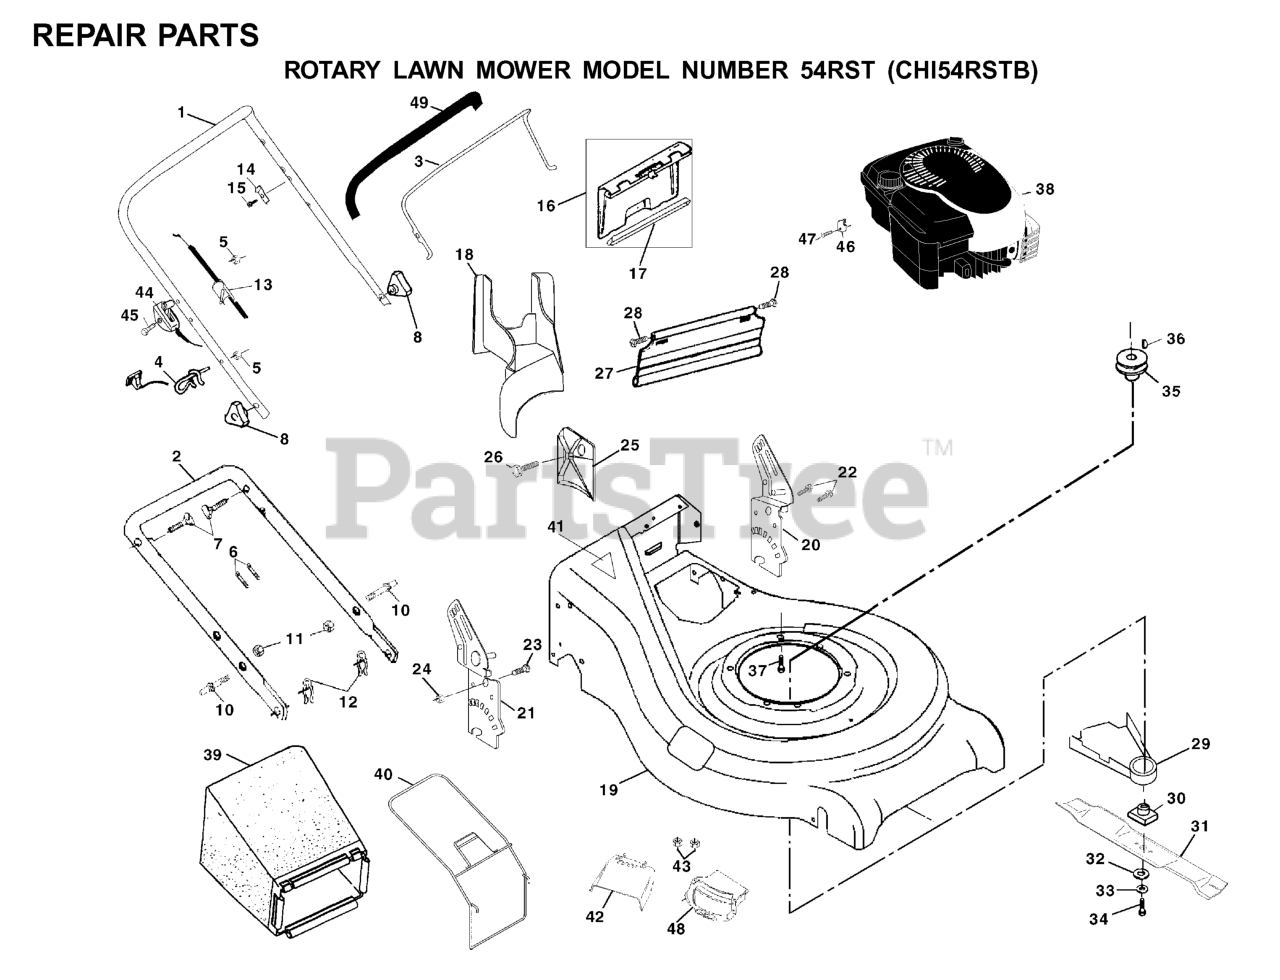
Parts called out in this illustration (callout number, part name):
1	HANDLE.UP.DLX.COMF.W/GRIP.GREY
2	HANDLE, LOWER
3	CONTROL BAR
4	ROPE GUIDE
5	NUT
6	TIE GUIDE
7	HANDLE BOLT
10	BOLT
11	NUT
12	HAIRPIN COTTER
13	ENGINE ZONE CONTROL
14	BRACKET UPSTOP
15	SCREW.HEX.HEAD.WASHER.10-16
16	KIT.DOOR.REAR.21.WRAPPED.BLACK
17	SEALING
18	MULCH PLUG
19	KIT-HOUSING
20	.RACKET
21	RIGHT HANDLE BRKT. ASSM.
22	SELF-TAPPING SCREW 5/16-18X3/4
23	BOLT, HEX HEAD 5/16-18
24	LOCKNUT
25	CLIPPING DEFLECTOR
27	REAR SKIRT
28	HINGE SCREW
29	DEBRIS SHIELD
30	BLADE ADAPTOR
31	21" MULCH BLADE PREMIUM
32	WASHER,HARDEN
33	LOCKWASHER
34	SCREW, HEX HD 3/8-24 X 1-3/8
35	ENGINE.PULLEY.FWG
36	HI PRO KEY PM WSL
37	BOLT 3/8-16X1-1/8
39	Grass Catcher Bag
40	FRAME.GRASS.CATCHER.WALK.21"
41	DECAL HYT
42	GUARD
44	THROTTLE TRIGGER
45	SCREW 1/4-20 X 2.12
46	CABLE CLAMP(ENGINE)
47	SCREW.HEX.HEAD.WASHER.10-16
48	MULCH COVER
49	GRIP.HANDLE.FOAM
